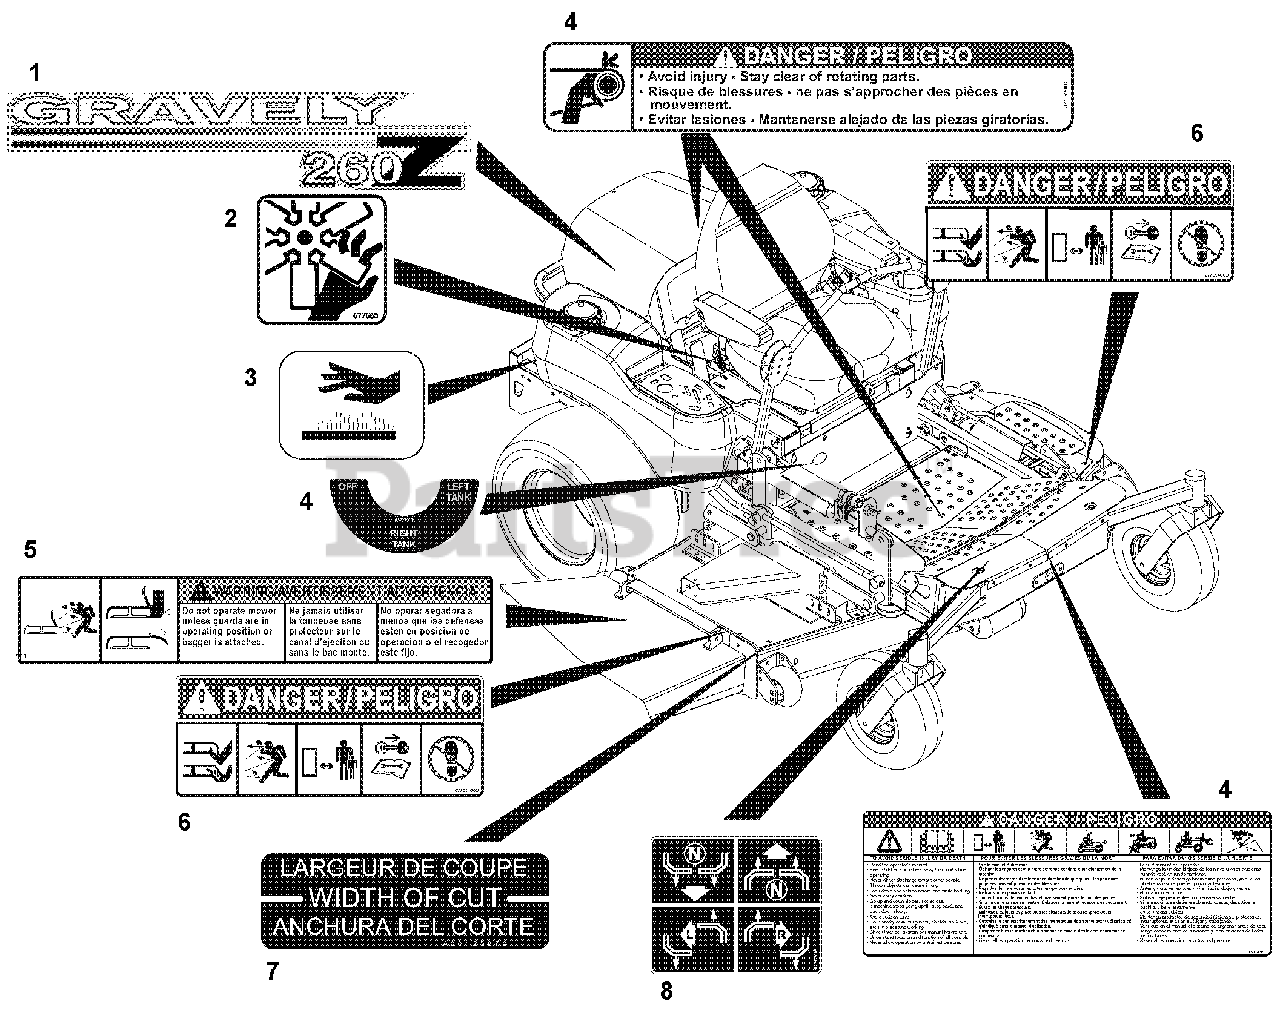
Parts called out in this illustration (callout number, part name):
1	Decal, PM-260Z Hood (067, 068, 069)
2	Decal, Danger Fan
3	Decal-Hot Surface
4	Set, Decal-Common Danger/Fuel
5	Decal, Warning
6	Decal, Mower Pan Head Danger
7	Decal, Width of Cut
8	Decal-Instructional
